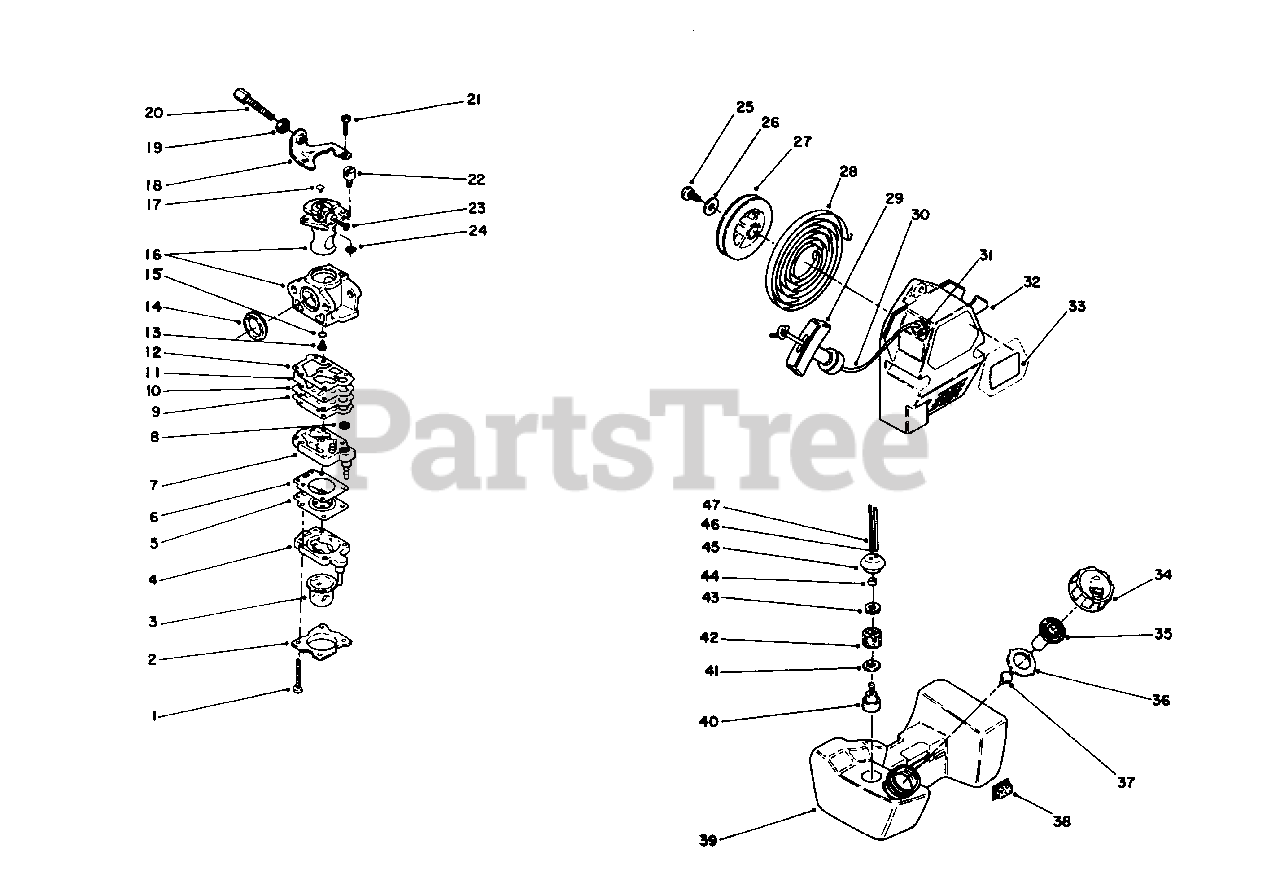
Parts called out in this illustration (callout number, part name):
2	Cover-Primer
3	Pump Assembly-Primer
4	Body-Primer
5	Diaphragm
6	Gasket-Diaphragm
7	Body-Pump
9	Gasket-Pump
11	Diaphragm
12	Gasket-Diaphragm
13	Jet-Main #43
14	Gasket-Rubber
15	O-Ring, Main Jet
16	Body-Carburator (Ref.)
19	Nut-Lock
20	Screw-Adjustment
22	Pivot-Cable
23	Valve-Throttle
29	Knob-Starter
30	Rope-Starter
32	Case-Starter
33	Decal-Toro
34	Cap-Fuel
35	Valve-Breather
37	Cap-Valve
39	Tank Assembly-Fuel
40	Weight-Filter
42	Filter-Fuel
43	Washer-Seal
45	Grommet-Fuel Tank
46	Hose-Fuel
47	Tube-Fuel Return
